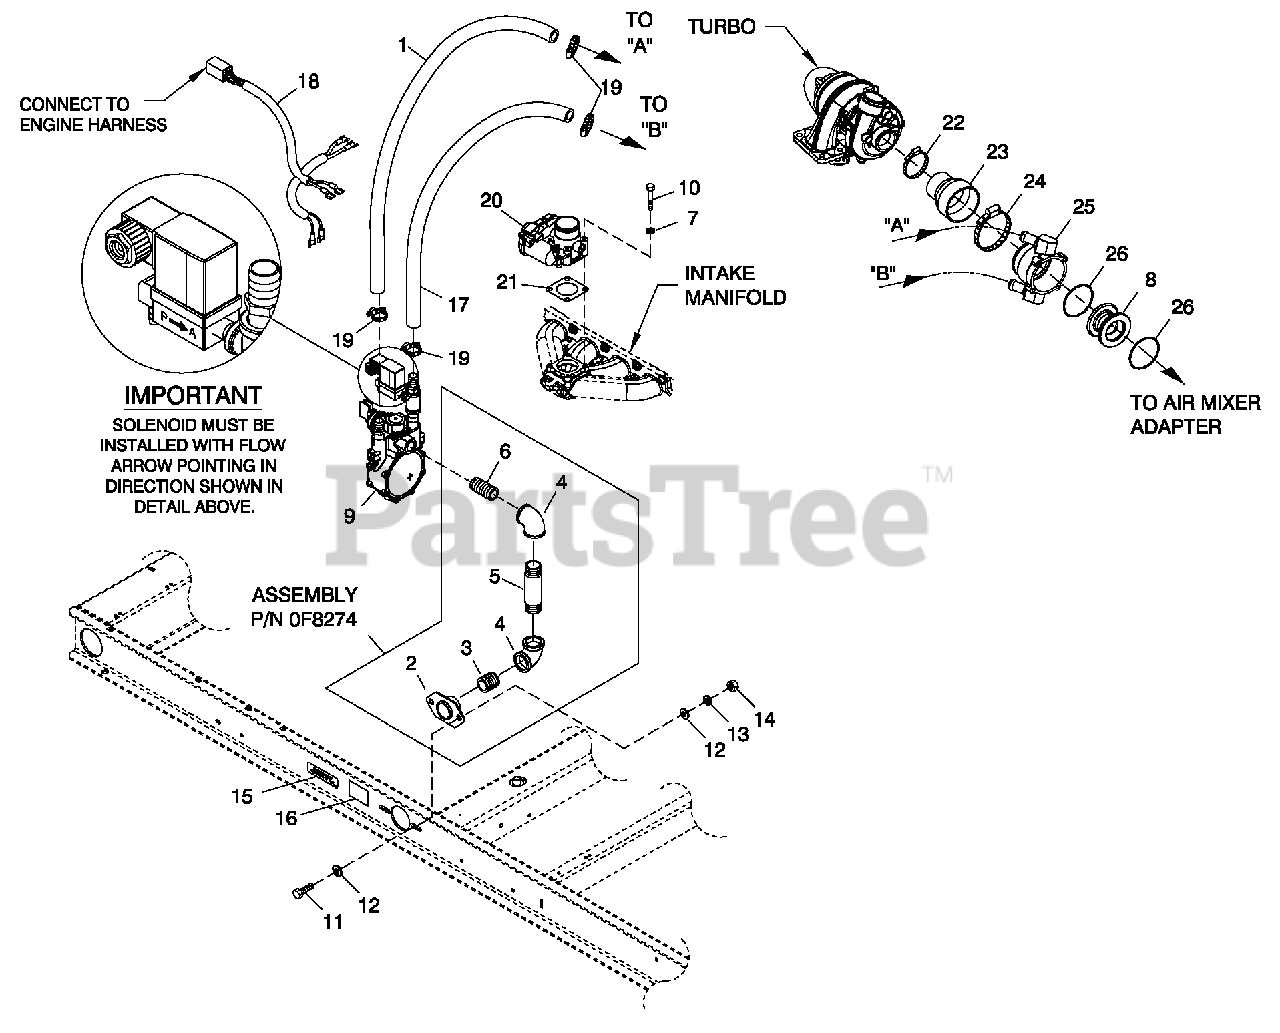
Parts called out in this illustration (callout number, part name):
1	HOSE 3/4 ID SAE-30R2 (45" LG)
2	FLANGE, FUEL INLET
3	NIPPLE CLOSE 3/4X1.375
4	ELBOW 90D 3/4N PT
5	NI P PLE PI PE 3/4 N P TX 7
6	NIPPLE CLOSE 3/4X1.375
7	WASHER LOCK M6-1/4
8	VENTURI THROTTLE 32MM
9	REG ASSY 2.4L 60KW LPV CPL
10	SCREW SHC M6-1.0 X 45 C12.9
11	SCREW HHC M8-1.25X 25 C8.8
12	WASHER FLAT 3/8-M10 ZINC
13	WASHER LOCK M8-5/16
14	NUT HEX M8-1.25 G8 CLEAR ZINC
15	DECAL FUEL INLET LPG
16	DECAL INLET PRESSURE
17	HOSE 3/4 ID SAE-30R2 (41" LG)
18	HARNESS FUEL JUMPER SINGLE REG
19	CLAM P HOSE #10 .56-1.06
20	ACTUATOR BOSCH 40 GOVERNOR
21	GASKET BOSCH 32
22	CLAM P HI TORQUE 1.75-2.625
23	REDUCER RUBBER 3.0"-2.00"
24	CLAM P HI TORQUE 2.75 - 3.625
25	MIXER 40/60MM ACTUATOR ASSY
26	O-RING 2-3/4X3/32X2-15/16
